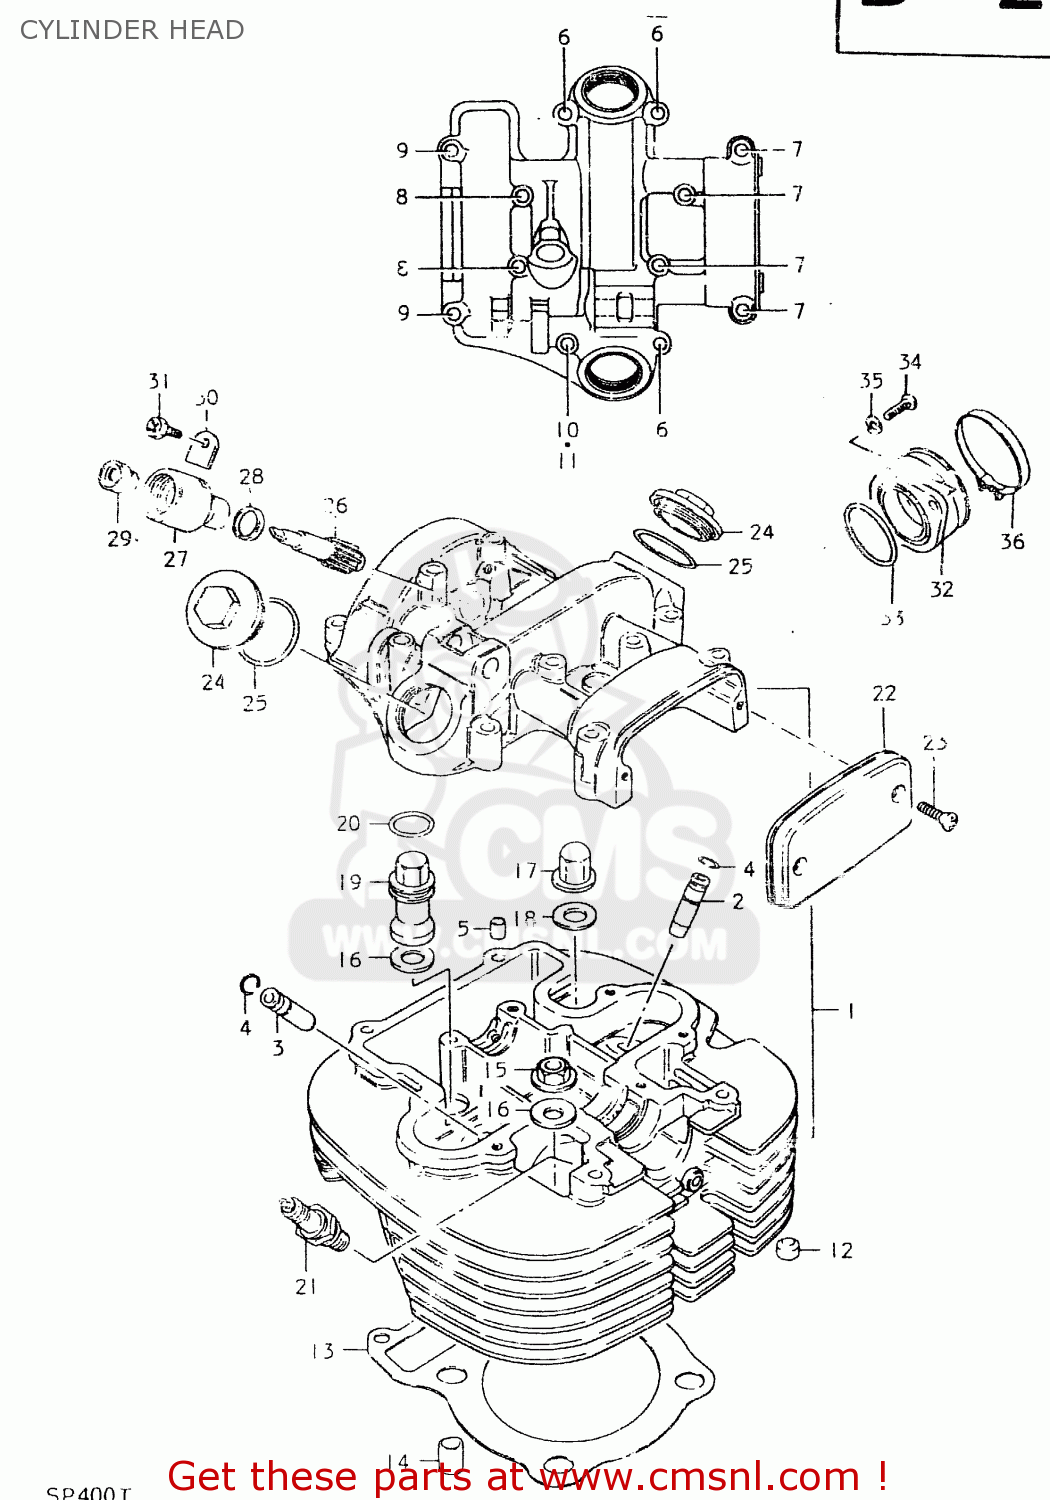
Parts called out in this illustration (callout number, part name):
1	HEAD SET,CYLINDER
2	GUIDE,INTAKE VALVE
3	GUIDE,EXHAUST VALVE
4	RING,SNAP
5	PIN(6.2X8X11)
6	BOLT 6X35
7	BOLT ,6X50
8	BOLT 6X65
9	BOLT(6X125)
10	BOLT (6X60)
11	GASKET (NAS)
12	PAD,CYLINDER
13	GASKET,CYLINDER HEAD (NAS)
14	PIN
15	NUT
16	WASHER(10.5X22X2.3)
17	NUT
18	GASKET (NAS)
19	NUT,CYLINDER HEAD SEAL
20	O RING(D:2.4,ID:17.8)
21	SPARK PLUG D8EA
22	CAP,CYLINDER HEAD COVER
23	SCREW
24	CAP,INSPECTION
25	O RING(D:3,ID:29.5)
26	GEAR,TACHOMETER DRIVEN
27	SLEEVE,TACHOMETER DRIVE
28	SEAL,TACHOMETER DRIVEN
29	SEAL,OIL(5X12X8)
30	PLATE,TACH DRIVE GEAR SLEEVE
31	SCREW(5X12)
32	PIPE,INTAKE
33	O-RING (D:2.4 ID:39.7)
34	SCREW
35	LOCK WASHER
36	CLAMP
